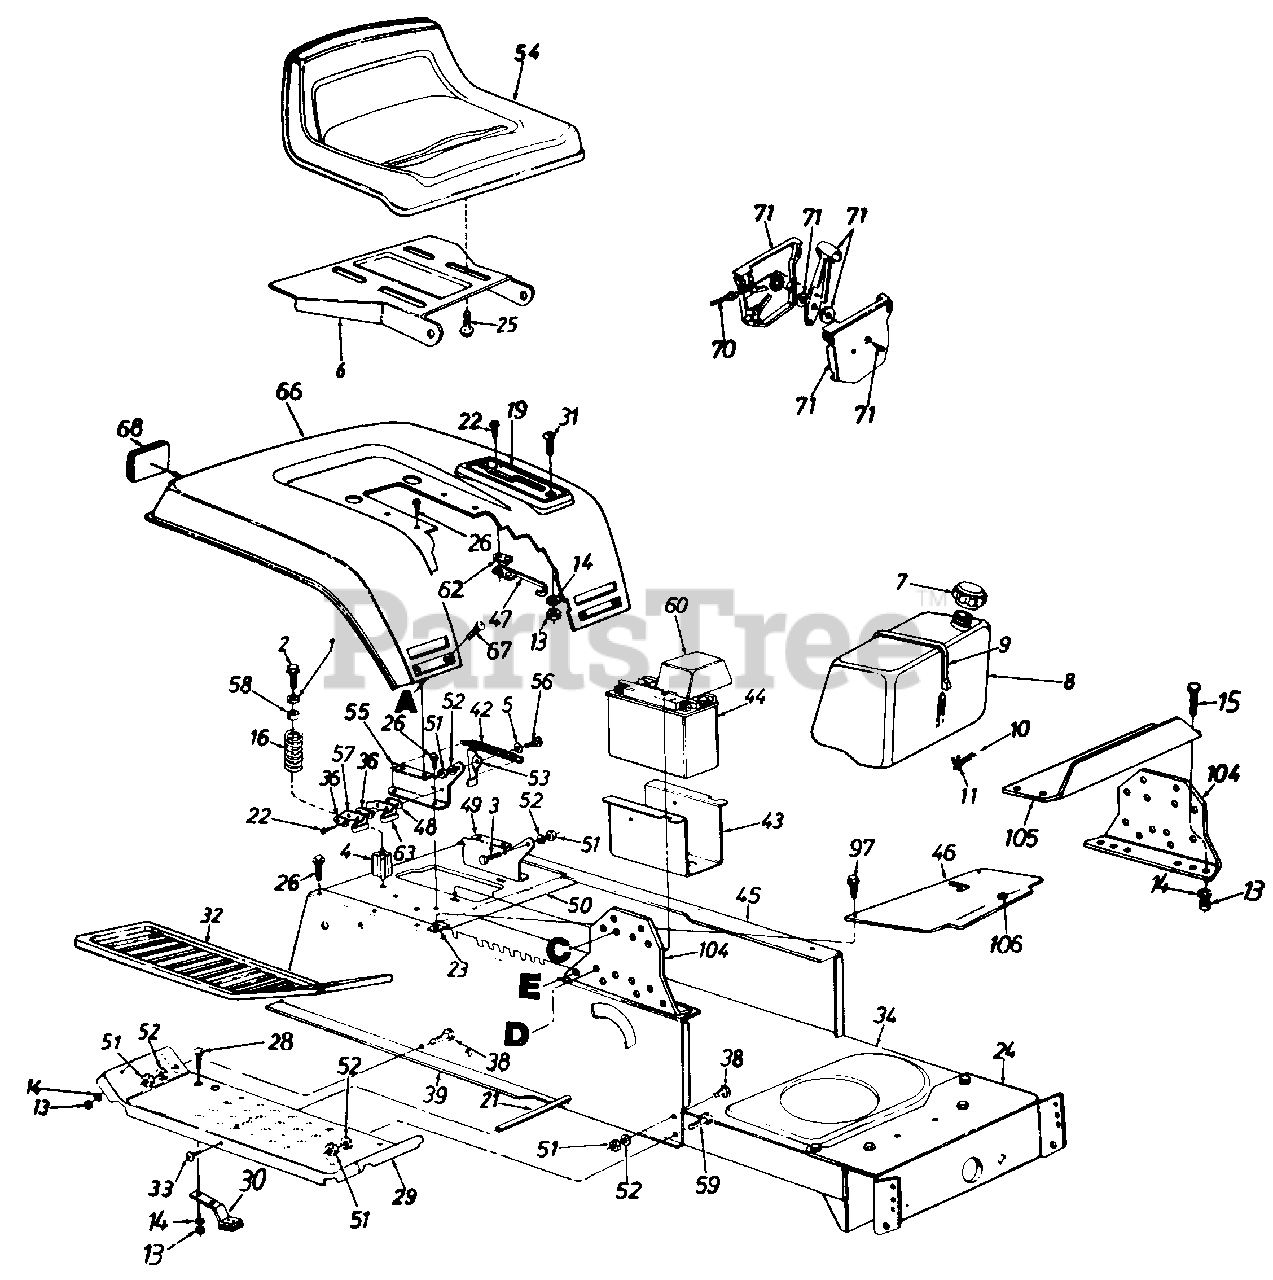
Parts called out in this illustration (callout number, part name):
1	Fl-Wash. .344" l.D. x .875"
2	Hex Wash. Hd. Tap Scr. 5/16-18 x 3.25" Lg.
3	Shld. Bolt .437" Dia. x .162"
4	Spring Spacer
5	Spr-Wash. .445" I.D. x .75
6	Seat Pivot Bracket
7	Fuel Cap w/o Gasket
8	Fuel Tank
9	Tie Strap
10	Fuel Line
13	Hex Nut 1/4-20 Thd.
14	L-Wash. 1/4n l.D.
15	Hex Bolt 1/4-20 X .62" Lg.
16	Compression Spring
19	Speed Control Index Brkt.
21	Running Board Rod
22	Hex Wash. Hd. AB-Tap Scr. #8 x 50" Lg.
23	Speed Nut #10Z
24	Front Pivot Brkt.
25	Hex Tap Scr. 3/8-16 x .75"
26	Hex Wash. Hd. AB-Tap Scr. 5/16 x .75" Lg.
28	Carriage Bolt 1/4-20 X .62n
29	Running Board
30	Blade Brake Ass'y.
31	Truss Mach. Scr. 1/4-20 X 75n Lg.
32	Rubber Foot Pad-L.H.
33	Truss Mach. Scr. 5/16-18 x .75" Lg.
34	Lower Frame
36	Insulator Plate
38	Hex Bolt 5/16-18 x 75" Lg.
39	483/N Upper Frame-R.H.
42	Extension Spring 5.31" Lg.
43	Battery Tray
44	12-V Battery (275 Cold Crank Amps)
45	483/N Upper Frame-L.H.
46	Shift Cover
47	Reverse Safety Switch
48	Insulator Boss Plate
52	L-Wash. 5/16" I.D.
53	Seat Lift Brkt.
56	Shld. Bolt .437n Dia. x .268"
57	Spring Switch
59	Hex Wash. Hd. Scr. 5/16-18 x .37" Lg.
60	Battery Cover
62	Insulator Nut Plate
63	Safety Switch
68	Reflector
70	Throttle Wire
71	Throttle Control Box Ass'y.
97	Truss Mach. B-Tap Scr. #10 x .5" Lg.
106	Snap Bushing
